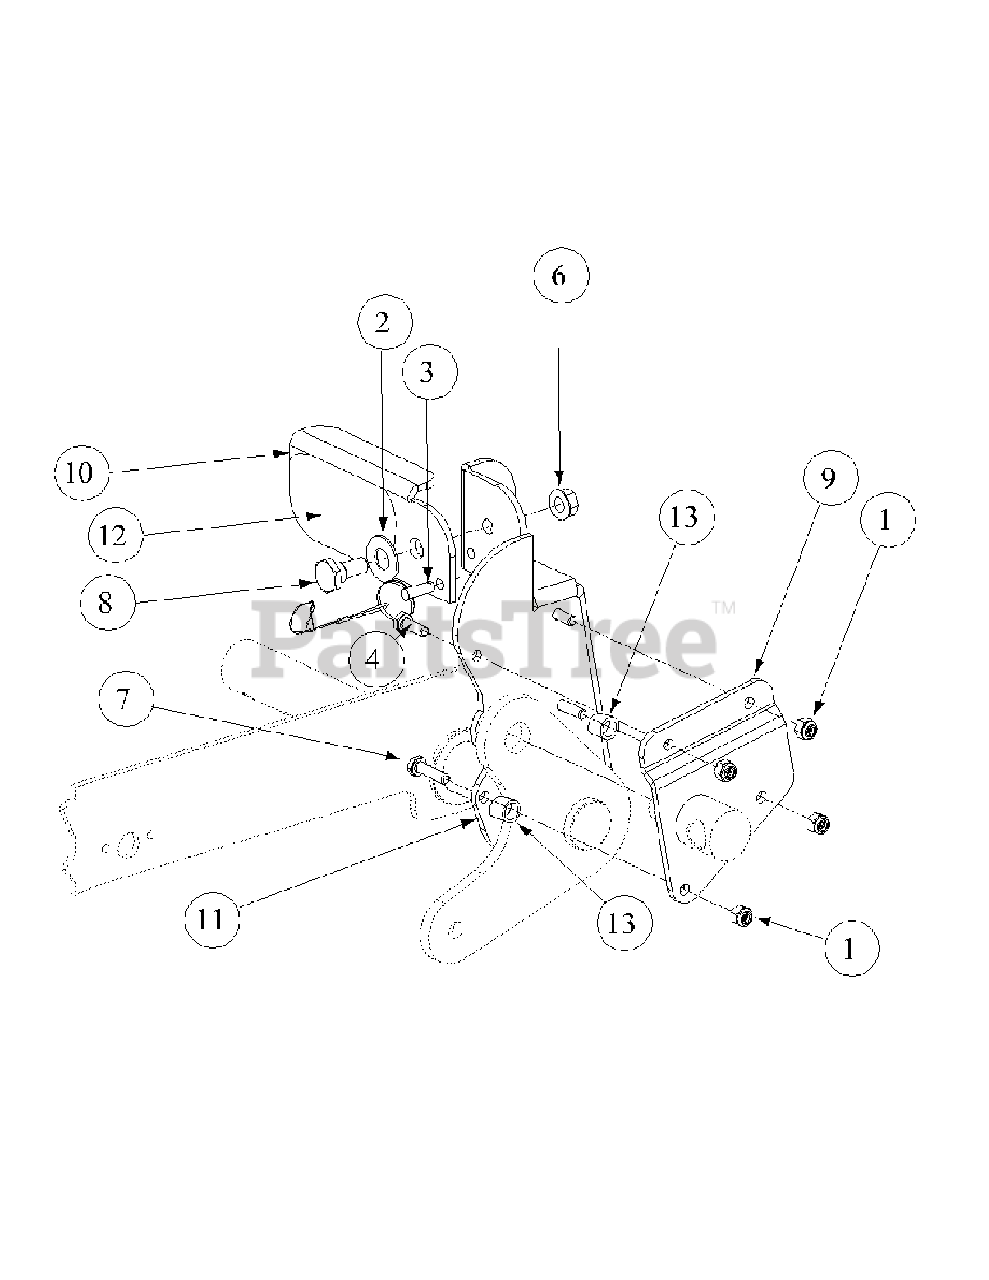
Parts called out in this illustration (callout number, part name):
1	Lock Nut, Nylon Insert, 1/4-20
2	Washer, 1/2 x 1 Shim
3	Detent Pin, w/12" Lanyard
4	Hex Cap Screw, 1/4-20, .75
6	Hex Nut, Flange Lock 3/8-16
7	Hex Cap Screw, 1/4-20, 1.00
8	Shoulder Screw, .50x.27 Lg., 3/8-16
9	Foot Lift Backup Pedal
10	Deck Foot Pedal Lift
11	Deck Foot Pedal Lift Holder
12	Deck Foot Lift Pad
13	Turnbuckle Sleeve
